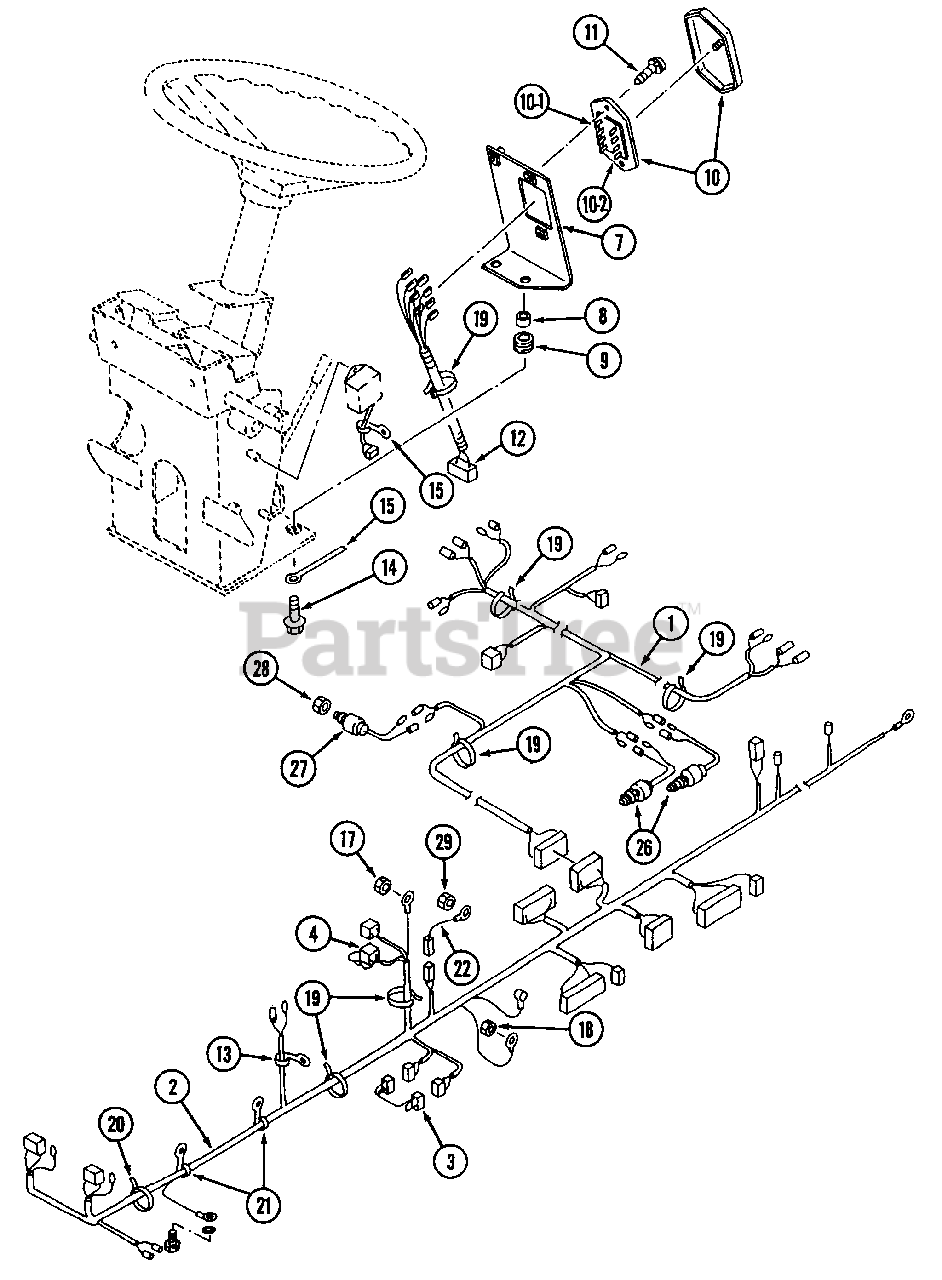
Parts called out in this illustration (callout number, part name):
7	Bracket, Fuse
10	Box, Fuse
26	Switch, Safety
27	Switch
